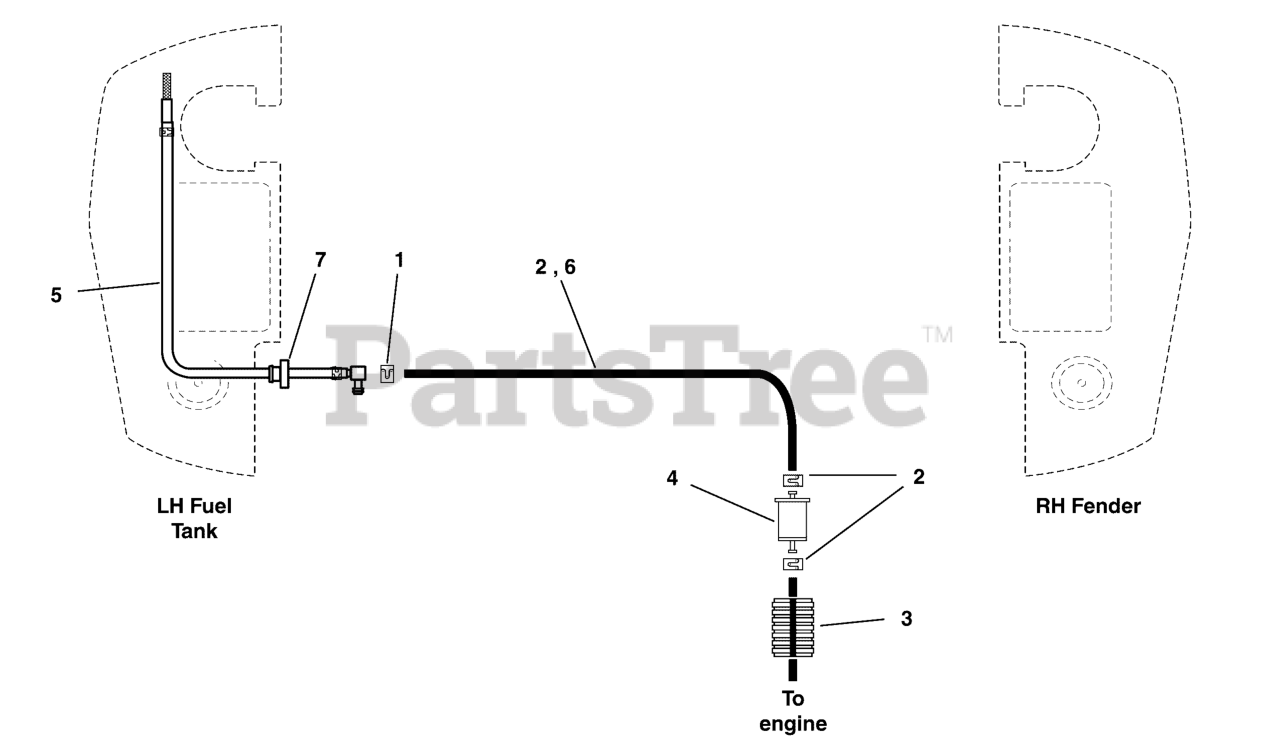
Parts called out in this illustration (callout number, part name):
1	CLAMP, Hose
2	Fuel Line, 25" Long (tank to filter)
3	WIRE LOOM, 1/2 ID, 13.00 LONG
4	FUEL FILTER (SV)
5	PICKUP TUBE ASM, FUEL TANK, 22"
6	1/4" Fuel Line, 5" Long
7	BUSHING-FUEL TANK RED RUBBER
